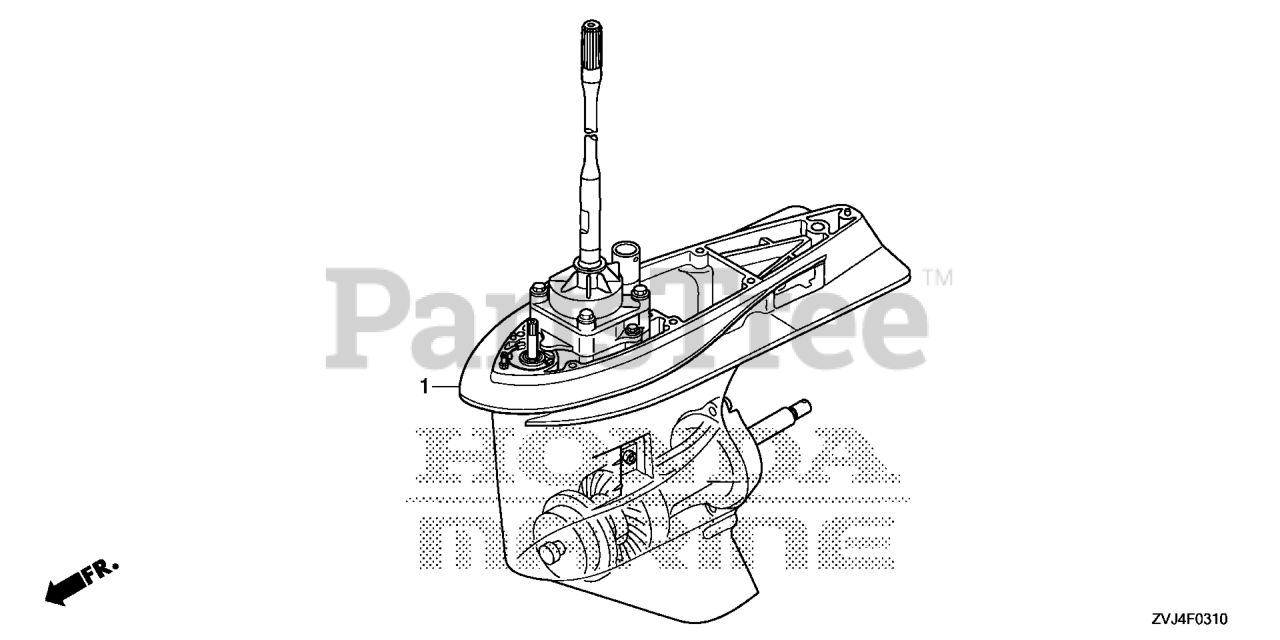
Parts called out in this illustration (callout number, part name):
1	CASE ASSY., GEAR *NH565* (UL)(COUNTER ROTATION) (GRAND PRIX WHITE)
1	CASE ASSY. *NH565*
1	CASE ASSY. *NHB14M*
